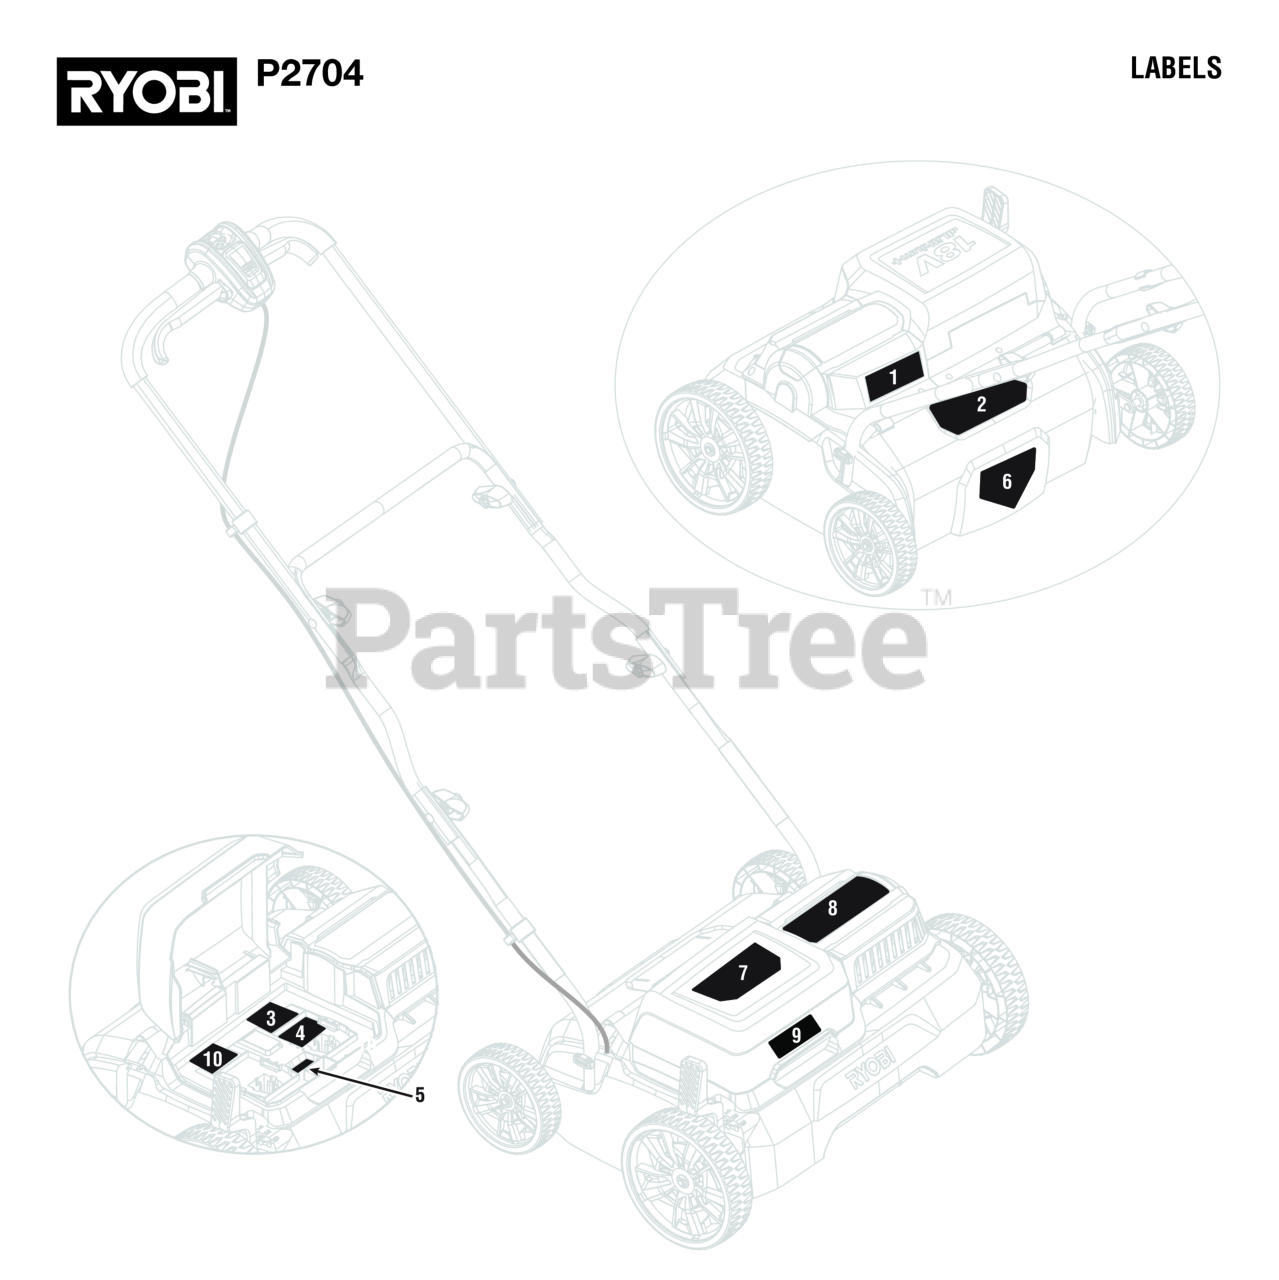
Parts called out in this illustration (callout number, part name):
1	Data Label
2	Icons\Warning Label
3	Key Warnings Label
4	Battery Wet Conditions Label
5	Start Key Label
6	Danger Label (No Hands/Feet)
7	RYOBI ONE+ HP Logo Label
8	ONE+ HP/Brushless Logo Label
9	14 in. Callout Label
10	Must Use 2X Batteries Label
